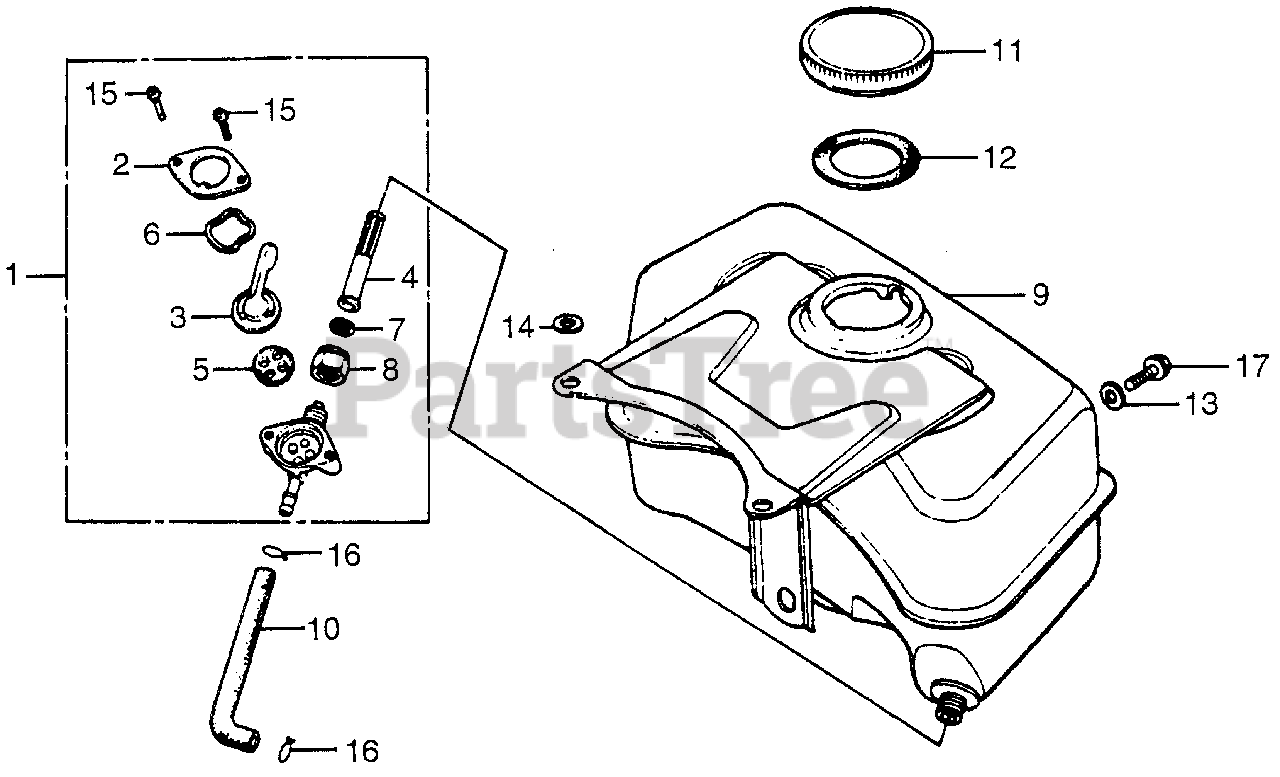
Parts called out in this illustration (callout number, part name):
1	PETCOCK ASSY. (NOT AVAILABLE)
2	COVER, PETCOCK (NOT AVAILABLE)
3	LEVER, VALVE (NOT AVAILABLE)
4	SCREEN, STRAINER
5	GASKET, VALVE
6	SPRING, PETCOCK LEVER
7	GASKET, FUEL STRAINER CUP
8	NUT, TURN BUCKLE (NOT AVAILABLE)
9	TANK, FUEL
10	TUBE, FUEL
11	CAP, FUEL FILLER
12	GASKET, FUEL FILLER CAP
13	WASHER (6MM)
13	WASHER, WHEEL (6MM)
14	WASHER (6MM)
15	SCREW, PAN (3X6)
16	CLIP, TUBE (B8)
17	BOLT, FLANGE (6X10)
